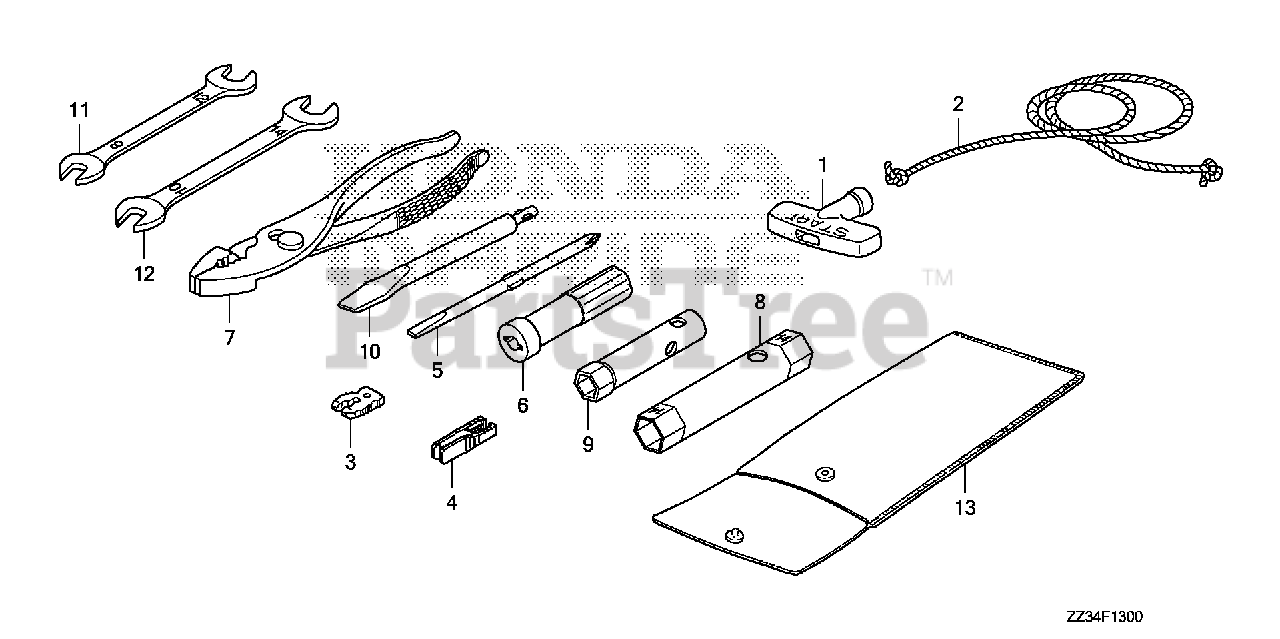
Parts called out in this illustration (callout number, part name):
1	GRIP, STARTER
1	KNOB, RECOIL SRARTER
2	ROPE, RECOIL STARTER (1300MM)
3	CLIP, EMERGENCY LOCK
4	PULLER, MINI FUSE (SUMITOMO)
5	SCREWDRIVER (NO.2 PHILLIPS -)
7	PLIERS (135) (RIKEN)
8	WRENCH, PLUG
9	WRENCH, BOX (10MM)
10	SCREWDRIVER, CHECK BOLT
11	SPANNER (8X12)
12	SPANNER (10X14)
